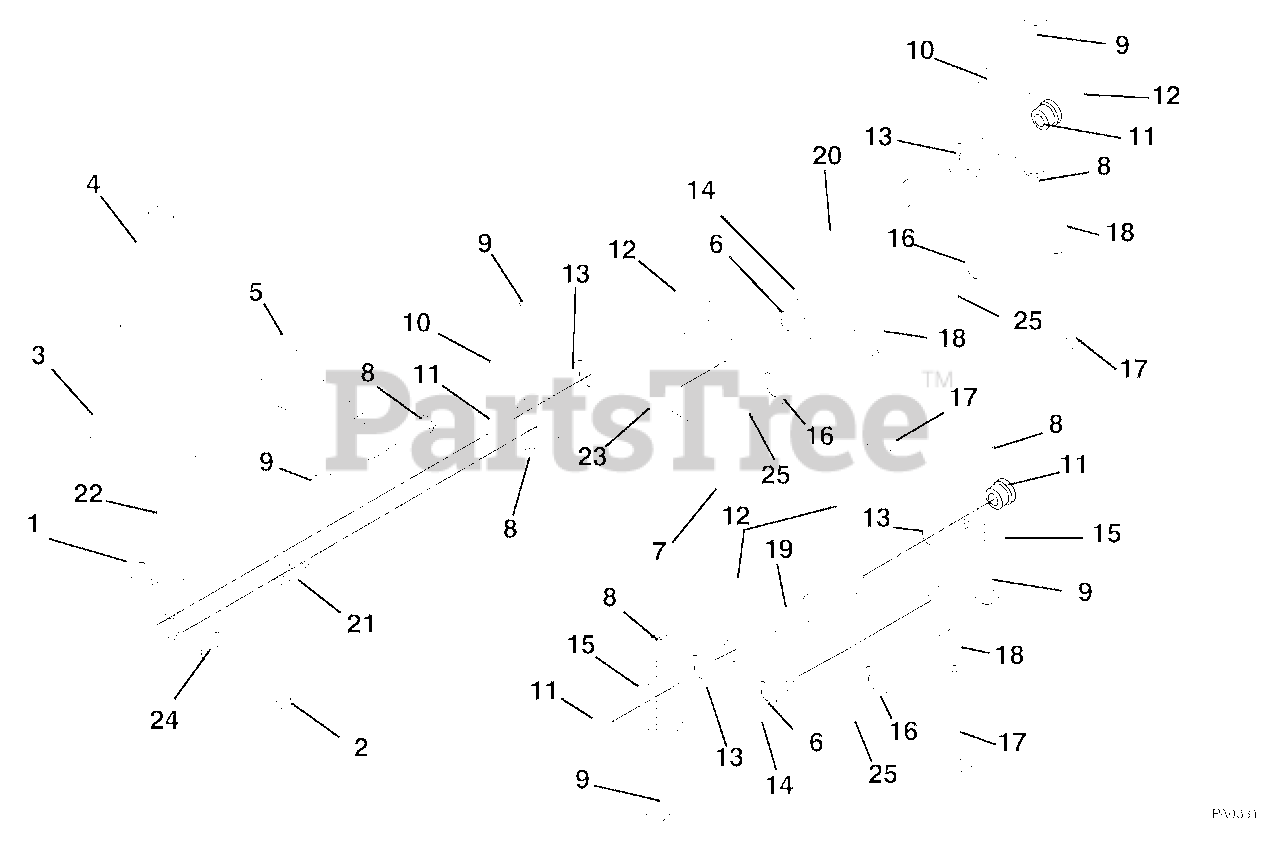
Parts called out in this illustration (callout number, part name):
1	Nut-Locking-Top-Flange .31-18
2	Bolt, 1.25 Socket Shoulder Plain
3	Weldment-Lift Handle
5	Detent Plate
6	Washer, Flat Steel .505 x 1.00 x .062
7	Rod, Deck Lift
8	Nut-Locking-Top-Flange .38-16
9	Bolt-Round Head Square Neck .38-16 x .75 Grade 5
10	Bracket, Lift
11	Bushing-Flange .75 x 1.00 x .625 x 1.25
12	Pin, Spring Clip
13	Washer, Flat Steel .563 x 1.38 x .109
14	Pin, Hair #16
15	Bracket, Deck Pivot
16	Washer, Flat Steel .511 x 1.44 x .125
17	Rod, Link (060, 062)
17	Rod, Link (064)
18	Trunnion (060, 062)
18	Trunnion (064)
19	Weldment, Front Lift (060, 062)
19	Weldment, Front Lift (064)
20	Weldment, Lift (060, 062)
20	Weldment, Lift (064)
21	Spring, Extension
22	Pin-Roll .25 x 1.25
23	Pivot, Rod
24	Washer, Flat Steel .43 x 1.00 x .160
25	Clip, Spring
